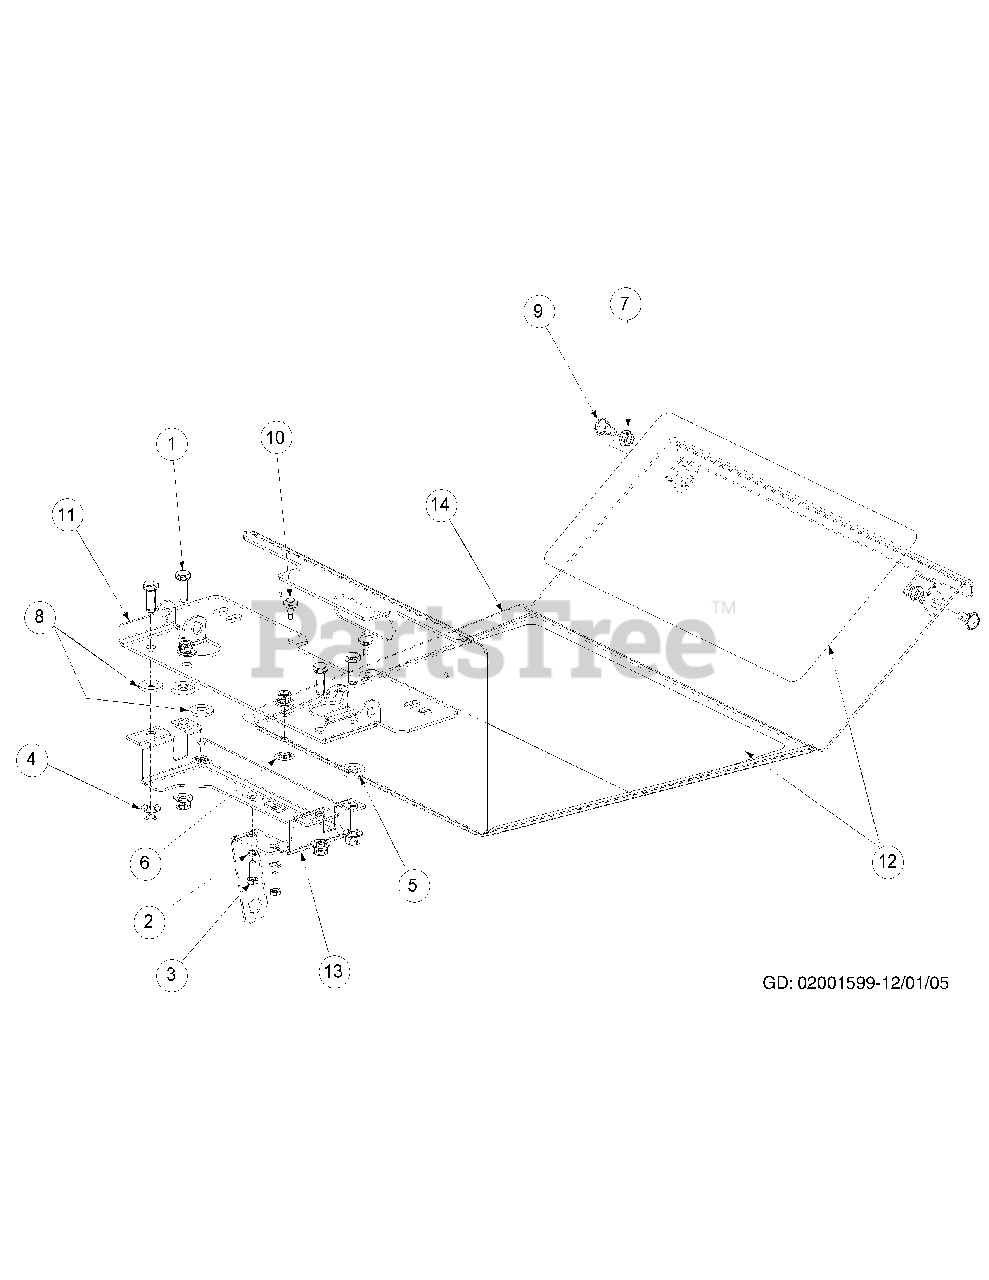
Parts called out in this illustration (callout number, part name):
1	Hex Cap Screw, 3/8-16, x 1
2	Lock Washer, 1/4
3	Hex Cap Screw, 1/4-20, .75
4	Hex Nut, Flange Lock, 3/8-16
5	Washer
6	Carriage Bolt, 3/8-16 x .75 Long
7	Lock Nut, Hex Flange, 5/16-18
8	Flat Washer, .406 ID, 1.0 OD, .105
9	Shoulder Screw, .435 x .350: 5/16-18
10	Rubber Bumper, .62 OD x .22 Thick
11	Panel Seat
12	Foot Abrasive Pad
13	Support, Seat Bracket
14	Floor Panel Assembly
